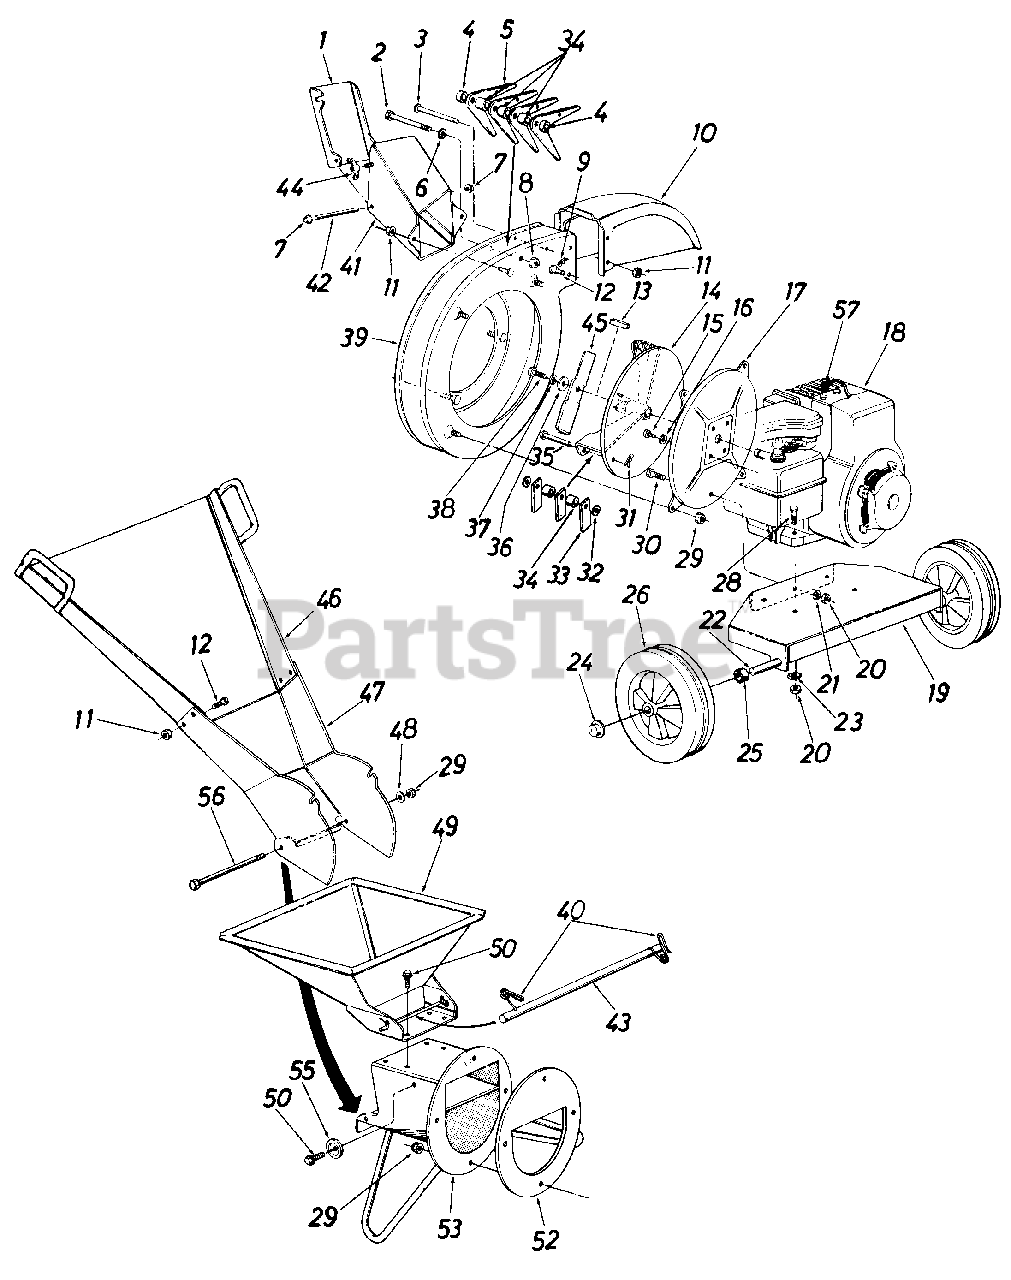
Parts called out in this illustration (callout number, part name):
1	Door Chip It
2	Hex Bolt 1/2-20 x 4.50" Lg.
3	Clevis Pin
4	Flail Spacer 7/32" Lg.
5	Cutting Finger
6	L-Wash. 1/2" I.D.
7	Palnut 3/16" Dia.
8	Hex Jam Nut 1/2-20 Thd.
9	Cotter Pin 3/32" Dia. x 3/4" Lg.
10	Chute Deflector
11	L.-Nut 1/4-20 Thd.
12	Hex Bolt 1/4-20 x .50" Lg.
13	Sq. Key 1/4" x 2.00" Lg.
14	Impeller Assembly
15	Hex Bolt 5/16-24 x 3/4" Lg.
16	L.-Wash. 5/16" I.D.
17	Hopper to Engine Mtg. Plate
18	Engine
19	Engine Mounting Plate
20	Hex Nut 5/16-24 Thd.
21	L.-Wash. 5/16" I.D.
22	Shaft
23	Special L.-Wash. 5/16" I.D.
24	Push Cap
25	Spacer
26	Wheel Ass'y.-Comp. (White)
28	Hex Bolt 5/16-24 x 1.50" Lg.
29	Elastic Lock Nut 5/16-18 Thd.
30	Hex Bolt 5/16-24 x .62" Lg.
31	Cotter Pin 1/8" Dia. x 1.00" Lg.*
32	Fl.-Wash. .531" I.D. x 937 O.D. x .09
33	Flail
34	Spacer 23/32" Lg.
35	Clevis Pin .50" Dia. x 3.0" Lg.
36	Fl.-Wash. .406" I.D. x 1.25" O.D. Hdn.
37	L.-Wash. 3/8" I.D. H.D.
38	Hex Bolt 3/8-24 x 2.0" Lg. H.T.
41	Chip-lt Guide Ass'y.
42	Hinge Pin
43	Release Bar
44	Wing Nut Elastic 1/4-20 Thd.
47	Lower Leaf Ramp Section
48	Fl.-Wash. 5/16" I.D.
49	Hopper Assembly
50	Hex Wash. Hd. Self-Tap Scr. 5/16-18 x .75" Lg.
52	Back-Up Plate
53	Inlet Guide Assembly
55	Stop Washer
56	Hex Bolt 5/16-18 x 8.38" Lg.
57	Spark Plug Boot
